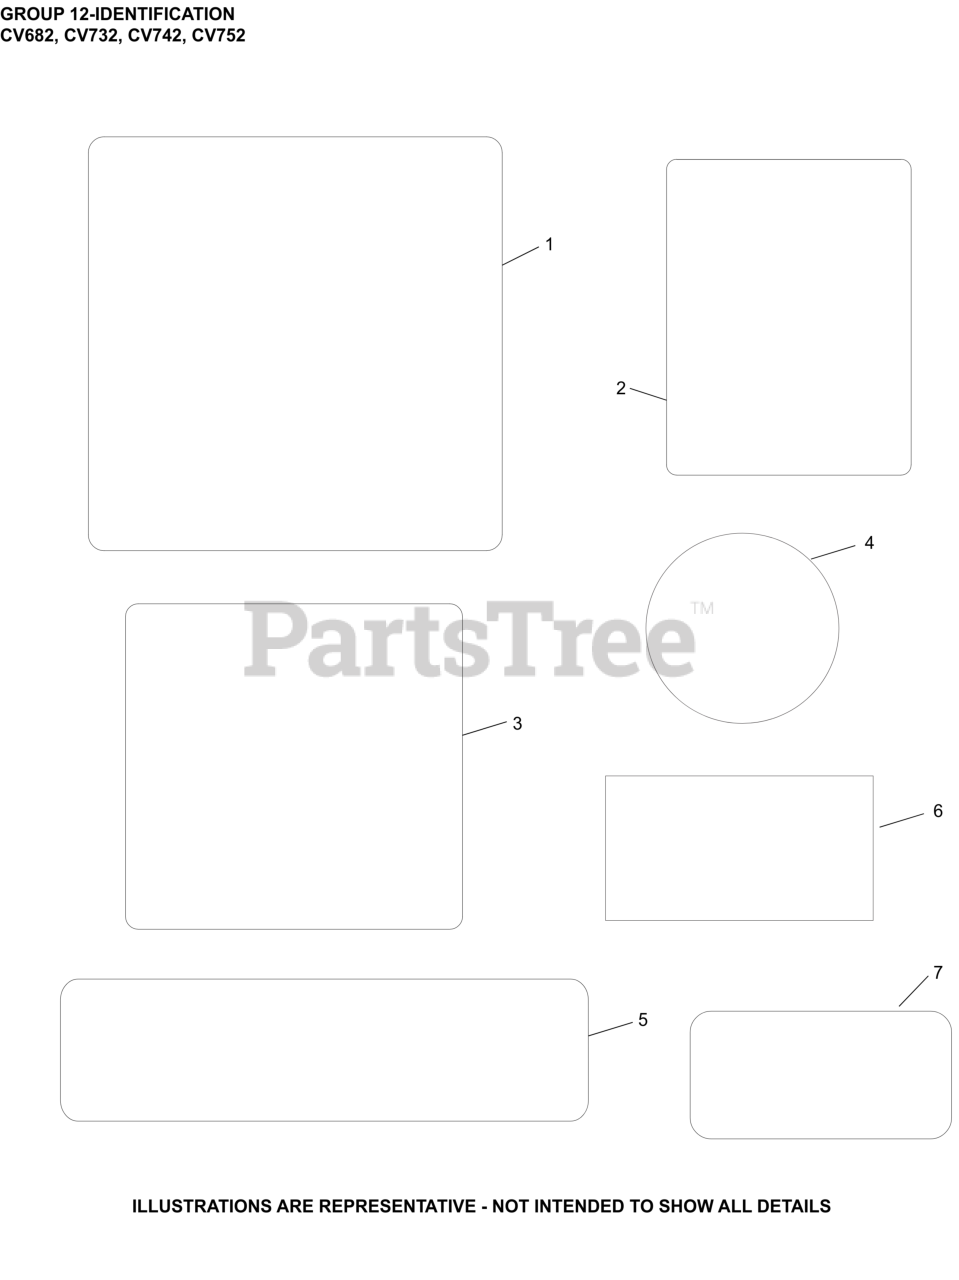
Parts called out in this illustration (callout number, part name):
2	LABEL, CLEAR LAMINATION
3	DECAL HDAC, 23.5 HP/747cc/CV-CH732
6	DECAL, USA
